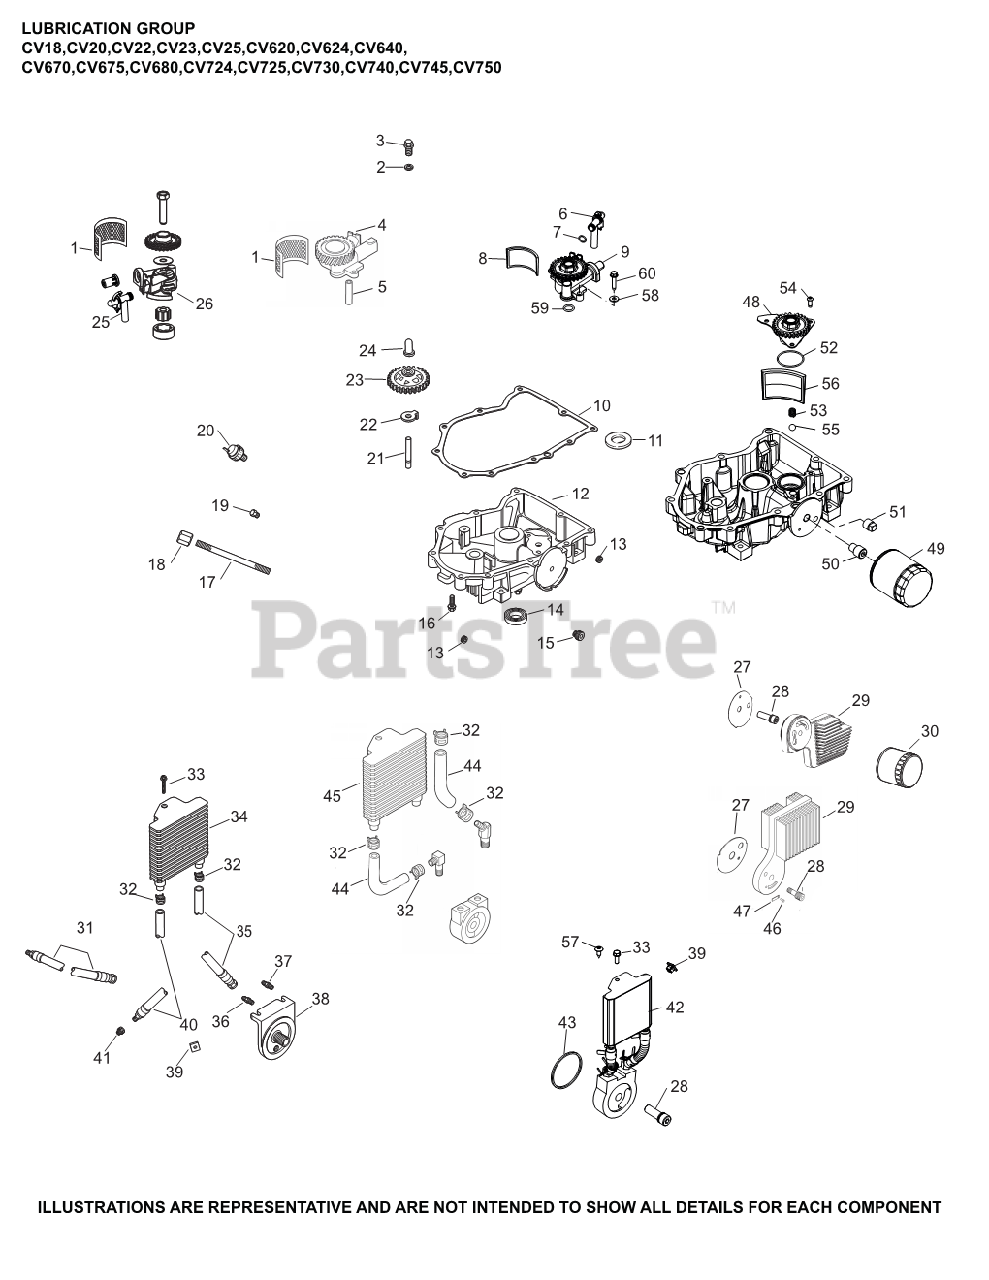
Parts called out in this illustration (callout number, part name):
10	GASKET, OIL PAN
12	KIT, OIL PAN ASSEMBLY
13	PLUG, PIPE CTSK 3/8"
14	SEAL, OIL
16	SCREW, FLG M8X1.25X45
19	PLUG, HD PIPE 3/8"
21	SHAFT, GOVERNOR GEAR
22	TAB, LOCKING
23	KIT, GOVERNOR GEAR W/PIN
24	PIN, GOVERNOR REGULATING
30	OIL FILTER
33	SCREW, TAP M6X1.7X18
39	NUT, PLASTIC - BLACK
48	PUMP, OIL ASSEMBLY
50	NIPPLE, OIL FILTER
52	O-RING (1.78" DIA)
53	SPRING, COMPRESSION
54	SCREW, BUTTON HEAD
55	PRESSURE RELIEF BALL
56	SCREEN, OIL
